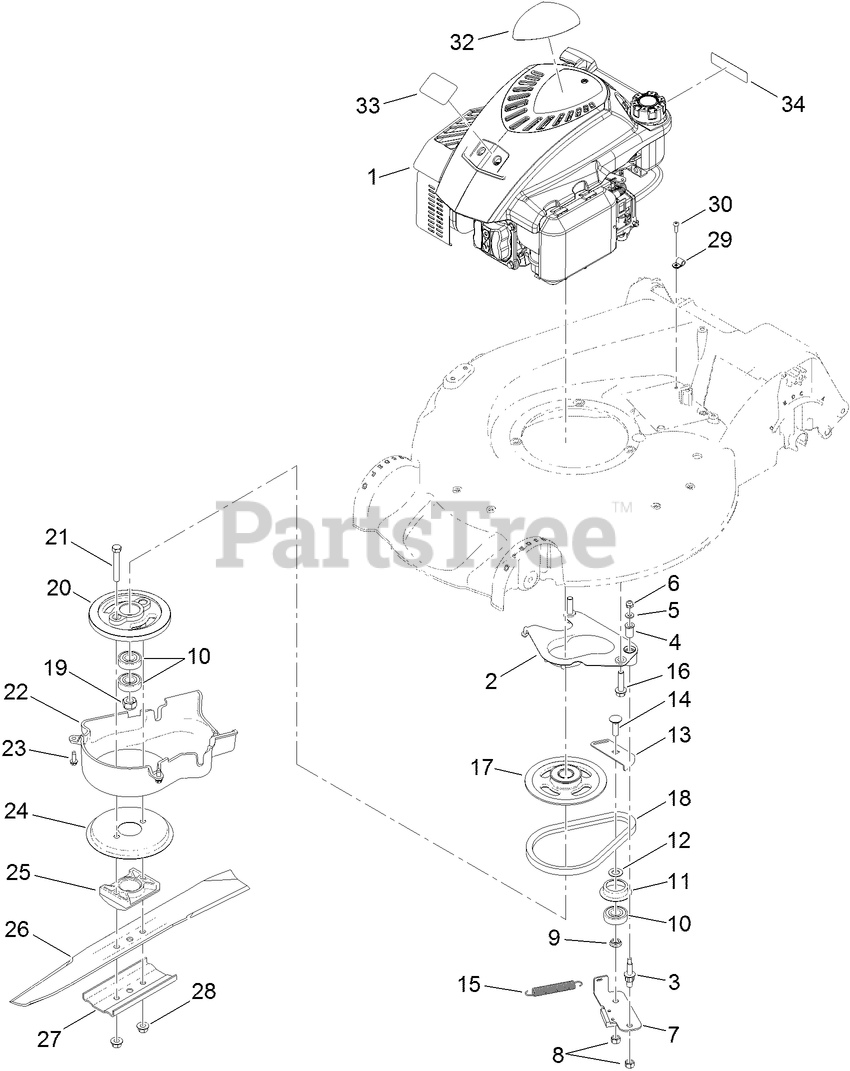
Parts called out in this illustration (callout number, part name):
1	ENGINE-1P65FC
2	PLATE-ANCHOR
3	BOLT-SHOULDER
4	BUSHING
5	WASHER-FLAT
6	NUT-LOCK, NI
8	LOCKNUT
9	SPACER-BEARING
11	RETAINER-BELT
12	SPACER
13	PLATE-GUIDE
14	BOLT-CARR
15	SPRING-TENSION, BRAKE
16	SCREW-HWH
17	PULLEY
18	BELT
19	NUT-HEX
21	SCREW-HH
23	SCREW-HWHTF
24	DISC
25	SUPPORT-BLADE
27	SUPPORT-BLADE
28	NUT-LOCK
29	CLAMP
32	DECAL-SHROUD
34	DECAL-ARRESTER, SPARK
